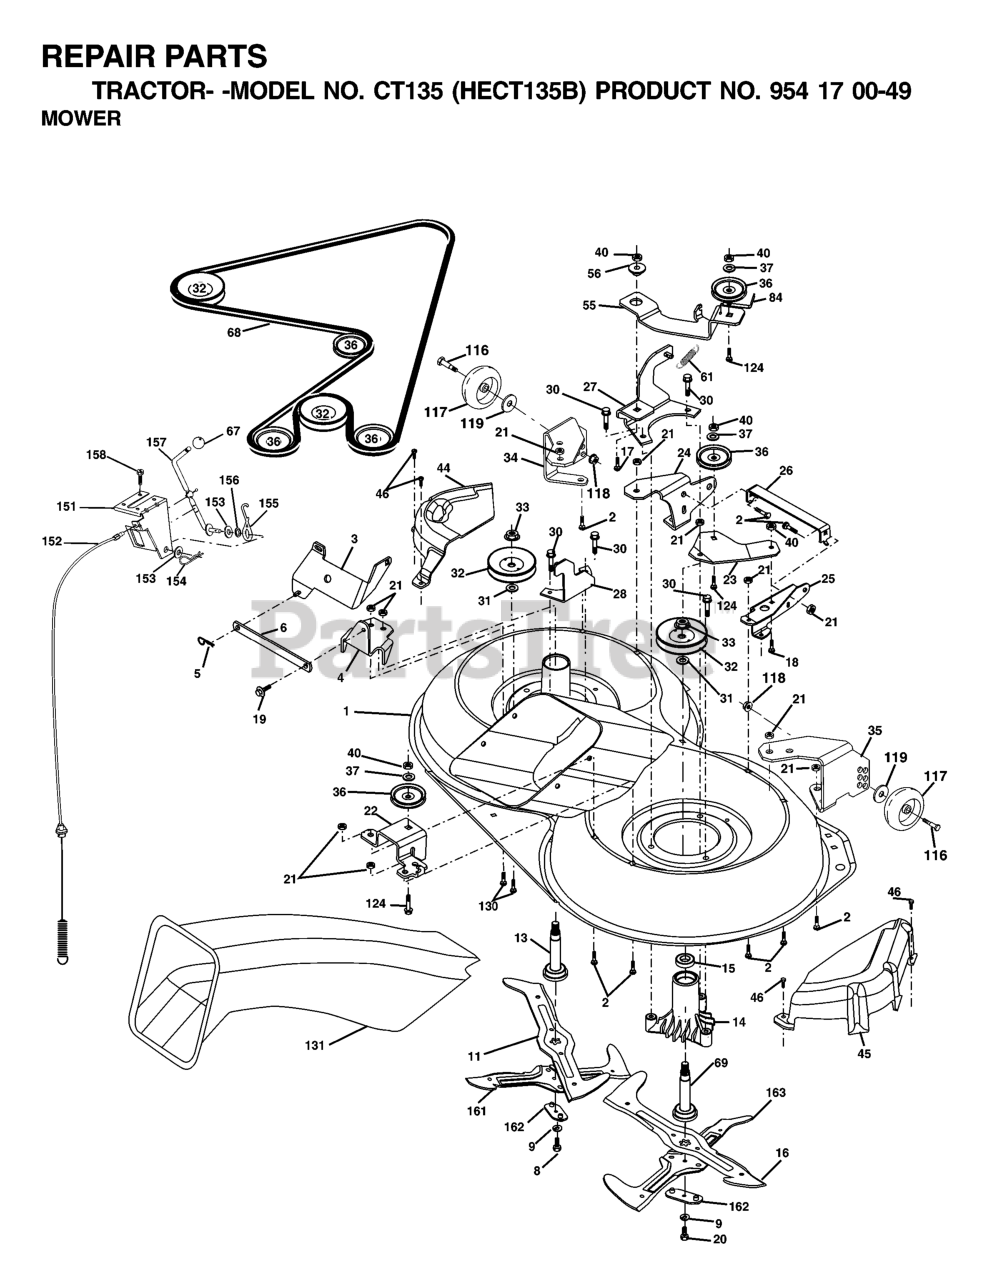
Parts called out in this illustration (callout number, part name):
1	MOWER HOUSING, DECK
2	RP BOLT 5/16-18 X3/4 ZN/YEL GR
5	RETAINER-SPRNG RB
6	BAR.SWAY.92.CRD
8	BOLT.3/8-24X1.25 GR8
9	LOCKWASHER
11	BLADE-LH 5PT STAR(CTH130)
13	SHAFT ASM VENT
14	HOUSING.MANDREL.VENTED (MACHD)
16	BLADE RH 6PT STAR(CTH130)
17	BOLT.3/8-14X1.25
18	BOLT D
19	BOLT SHD 5/16-18
20	BOLT.3/8-24X1.25GR8. LHTHRD
21	LOCKNUT
26	BRACE.SUPT.SUSP.FRT.CRD
30	SCREW, WASHER HEAD
31	WASHER
32	PULLEY, MANDREL
33	NUT, FLG TOPLOCK 9/16"
36	PULLEY.IDLER.4.25
37	WASHER
45	COVER.MANDREL.RH.CRD
46	SCREW.1/4-20X5/8
56	SPACER.RETAINER.MOWER
61	SPRING.TENSION.BELT
67	KNOB T (3/8 HOLE)
68	HEX-BELT
69	SHAFT.ASM.W/LWR.BRG.RH.THREAD
84	KEEPER, BELT IDLER
116	BOLT, SHOULDER
117	WHEEL GAGE DONUT
118	LOCKNUT
119	WASHER.5/16.FLAT.STE.STD.
124	BOLT.3/8-16X1.50
130	BOLT.CARR.SQNK.5/16-18UNC.X3/4
131	CHUTE BAGGER
151	BRACKET.CLUTCH.CABLE
153	WASHER FLAT 3/8"
154	SPRING RETAINER
155	SPRING RETENTION LEVER
156	SPACER.CLUTCH.CABLE
157	ROD CLUTCH CABLE 3/8"
158	SCREW
162	ADAPTER.BLADE.PNT.CSS.36/38/42
